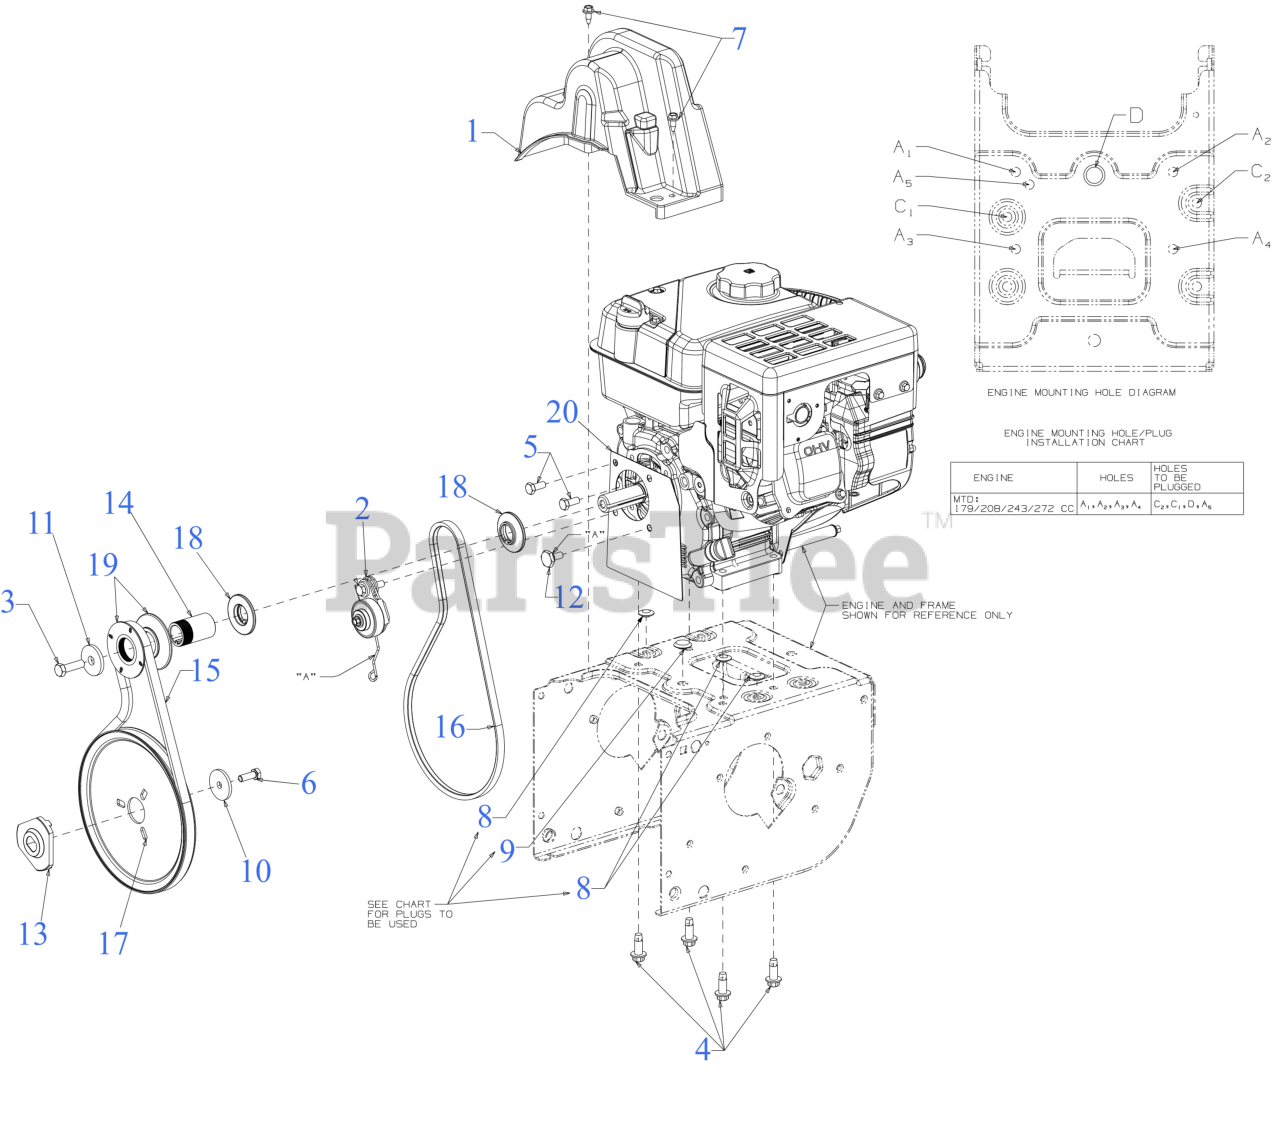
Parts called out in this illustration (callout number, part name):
1	BELT COVER SERVICE KIT (631-05322)
1	BELT KEEPER COVER BRACKET
1	HEX SCREW #12-16 x .50
2	IDLER ASSEMBLY
3	SCREW 3/8-24X1.25
4	SCREW 3/8-16 x 1
5	SCREW 5/16-24 x .750 GR5
6	SCREW 5/16-24 x .875 GR5
7	SCREW 1/4-20X.625
8	PLUG-3/8 DIA ID x 3/32
9	PLUG-1/2 ID x 3/32
10	FLAT WASHER
11	FLAT WASHER .45 x 1.5 x .172 HT
12	SHOULDER SCREW
13	ADAPTER PULLEY .75 DIA W/DD
14	PULLEY SPACER
15	V-BELT .500 x 35.00LG
16	V-BELT 3L 34.18
17	AUGER PULLEY
18	HALF PULLEY-3/8 V x 1.7160
19	HALF PULLEY A2.76 x 1.140 SPLINE
20	COVER PLATE
